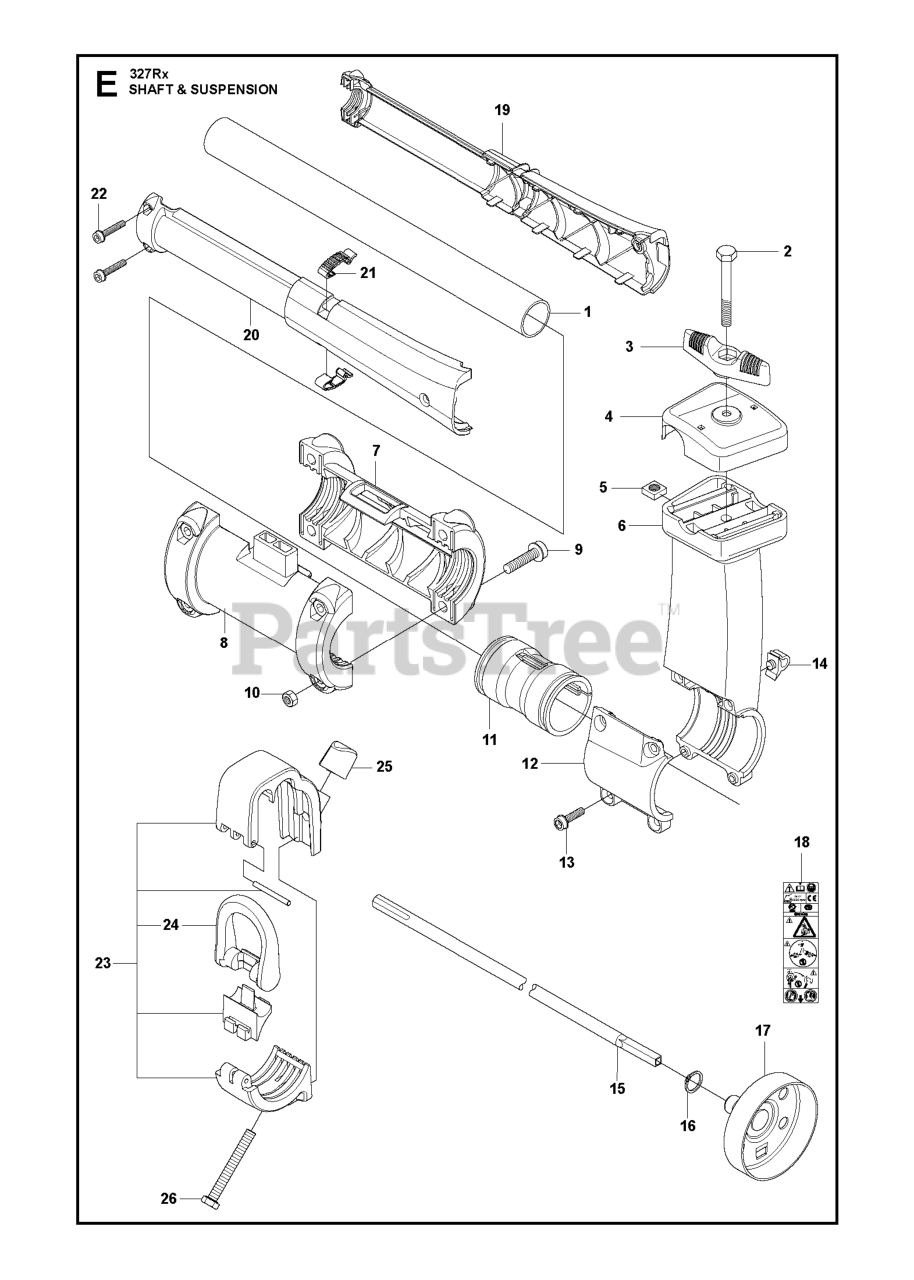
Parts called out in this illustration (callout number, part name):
1	DRIVE TUBE ASSEMBLY
2	%SCREW
4	PROTECTOR CLAMP
6	BRACKET
7	CLAMPING SLEEVE RIGHT Ã~24 GRE
11	VIBRATIONS ABSORBER
12	COVER, BRACKET
15	DRIVE SHAFT
16	RETAINING RING SGA 10
17	CLUTCH DRUM
18	LABEL WARNING TRIMMERS AND BRU
26	SCREW M6S 5X40
